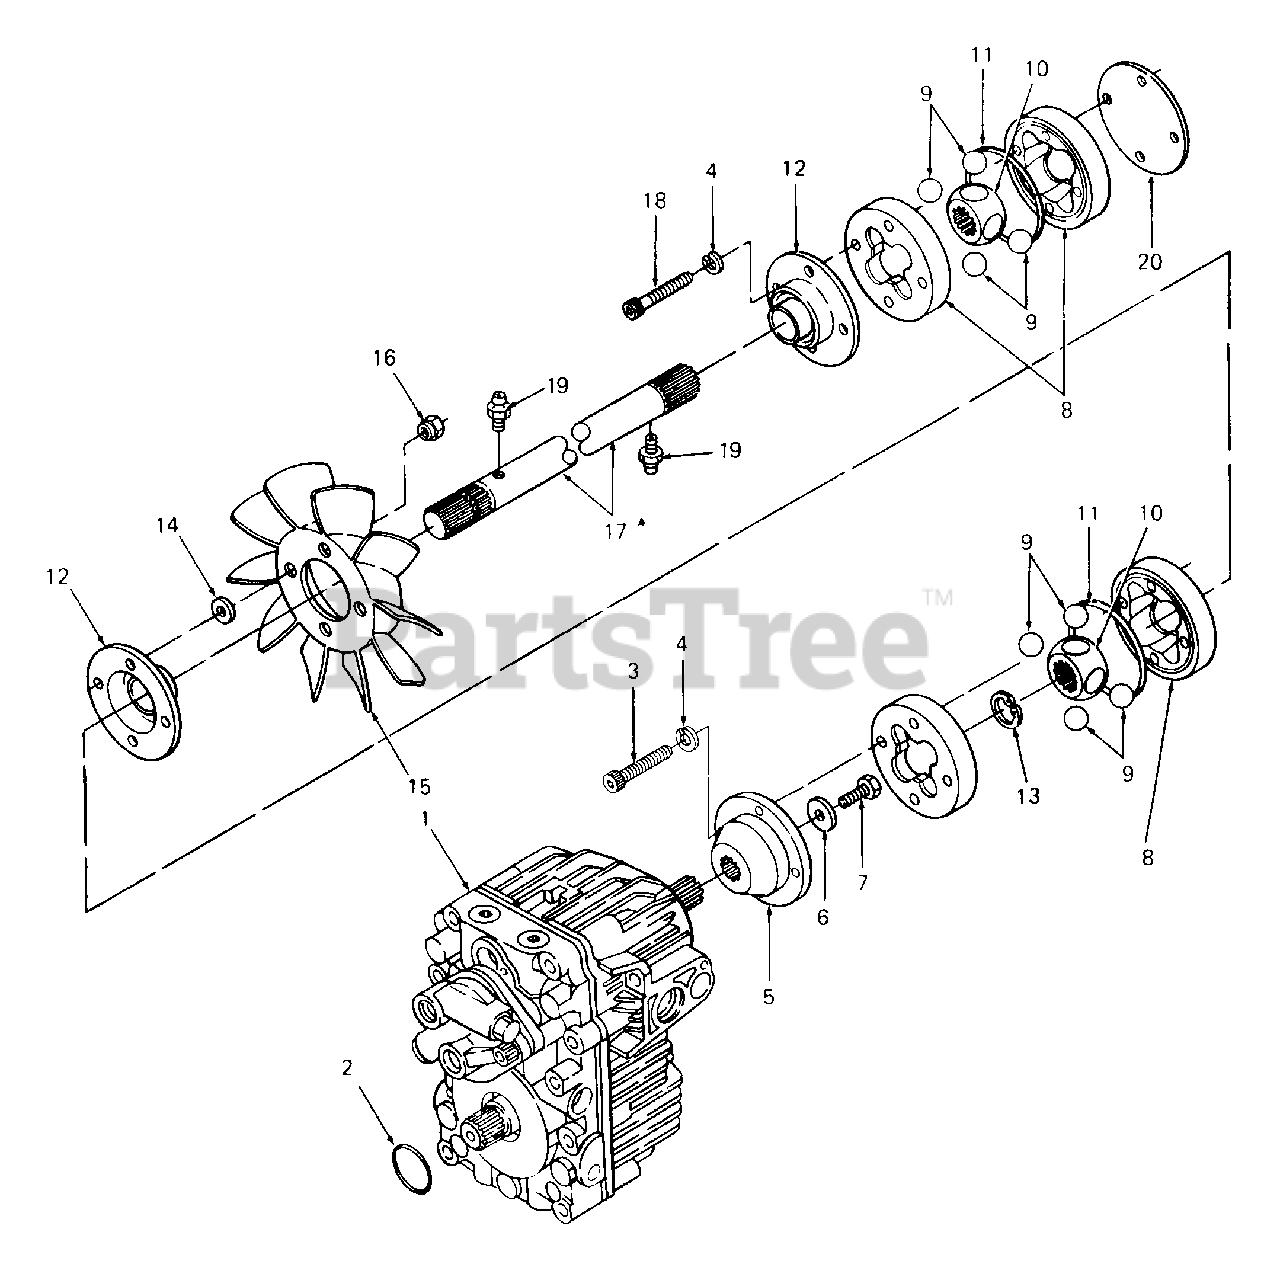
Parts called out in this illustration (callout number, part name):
1	Pump, Hydrostatic
2	O-Ring, 2.75 ID X .103 Dia
3	Screw, Socket Hd Cap, 1/4-20 X 2.0 Lg
4	Washer, Lock, 1/4
5	Adapter, Pump
6	Washer, Bell, .265 X .75 X .062 Thk
7	Bolt, Hex Patch, M6-1.0 X 20 MM Lg GR10.9
8	Coupling, Drive w/ O-Ring Groove
9	Ball, Steel, 5/8 Dia Chrome
10	Hub, Drive
11	O-Ring, 2.489 X .070
12	Boot, Coupling
13	Ring, Snap
14	Washer, Flat, .25 X .62 X .052 Thk
15	Fan, 10 Blade Hydro
16	Nut, Fan, 1/4-20
17	Shaft, Drive, 18.0 Lg
18	Screw, Socket Hd Cap, 1/4-20 X 1.75 Lg
19	Fitting, Grease
20	Cover, Coupling
